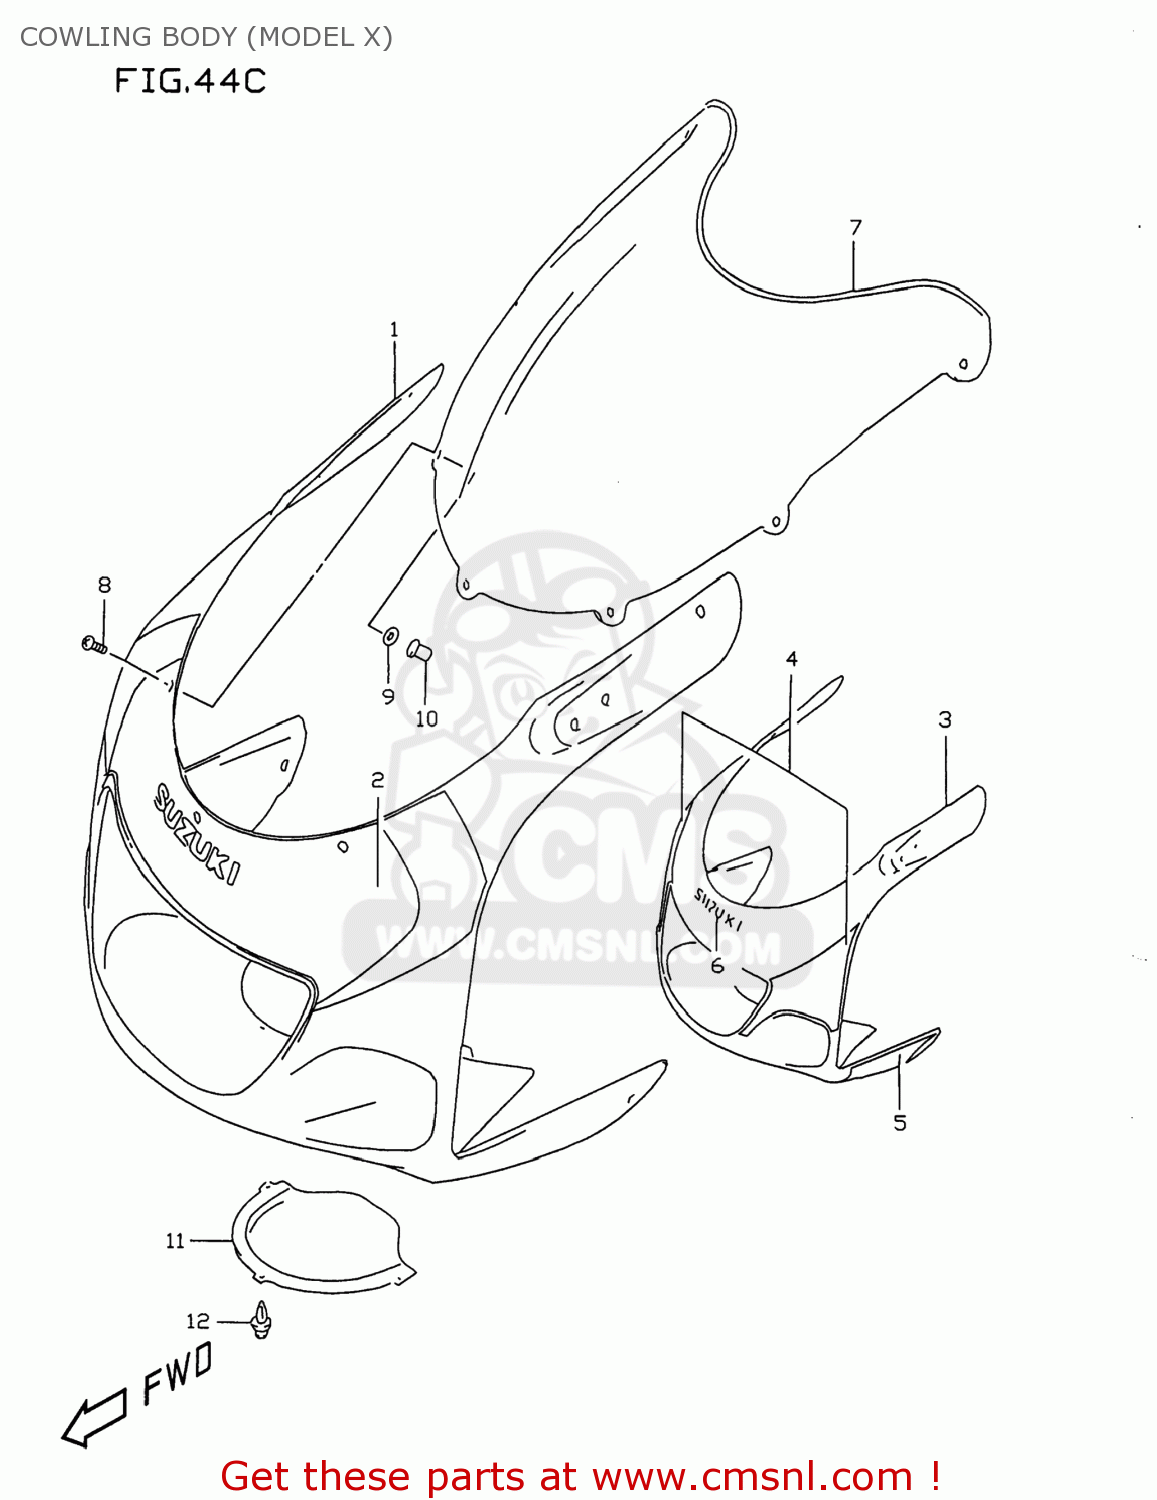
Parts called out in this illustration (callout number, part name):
1	COWLING ASSY,BODY
2	TAPE SET,COWL BODY FR
3	COWLING ASSY,BODY(RED)
4	TAPE SET,COWLING BODY
5	TAPE SET,COWLING BODY SIDE
6	EMBLEM,SUZUKI
7	WINDSCREEN
8	SCREW(5X14)
9	WASHER
10	NUT
11	LID,BODY COWL LWR
12	CLIP(BLACK)
